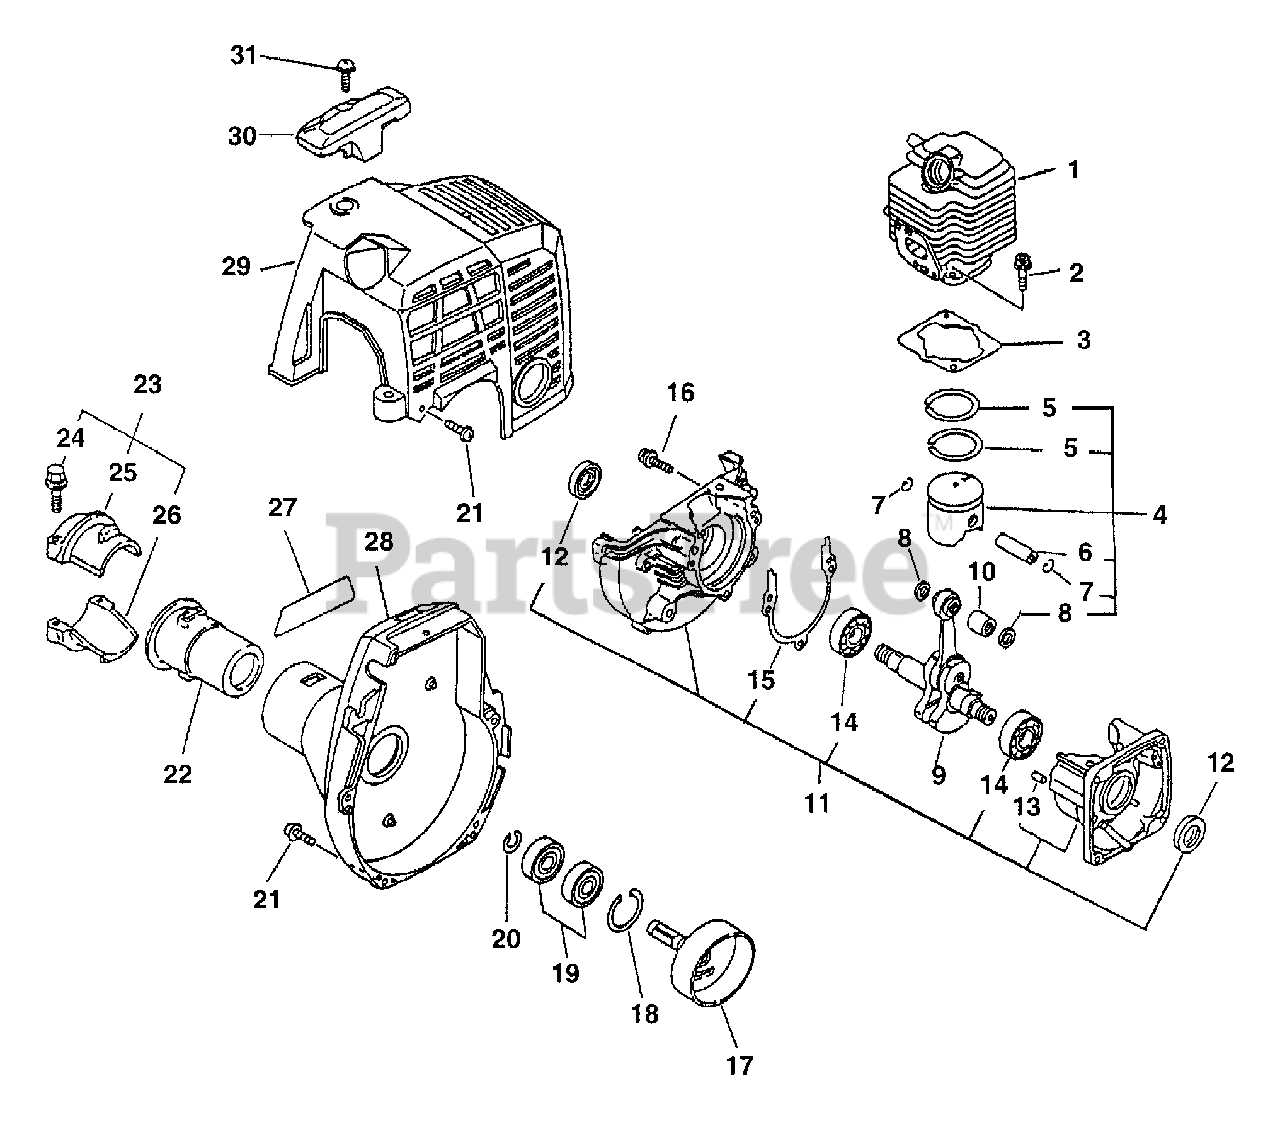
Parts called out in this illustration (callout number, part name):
1	CYLINDER KIT
2	SCREW - 5X22
3	GASKET, CYLINDER
4	PISTON KIT
5	RING, PISTON
6	PIN, PISTON
7	RING, RETAINING
8	SPACER, PISTON
9	CRANKSHAFT ASSY
10	BEARING, NEEDLE
11	CRANKCASE KIT
12	SEAL, OIL
13	PIN - LOCATING
14	BEARING, BALL - 6201
15	GASKET, CRANKCASE
16	SCREW - 5X28
17	DRUM, CLUTCH
18	RING, RETAINING - 28
19	BEARING, BALL - 6001
20	RING, RETAINING - 12
21	SCREW - 4X16
23	MAIN PIPE CLAMP KIT
24	BOLT - 5X25
25	CLAMP, MAIN PIPE - UPPER
26	CLAMP, MAIN PIPE - LOWER
27	LABEL - MODEL SHC-2401
28	CASE, FAN
29	COVER, ENGINE
30	GUARD - TOP
31	SCREW - 5X16
